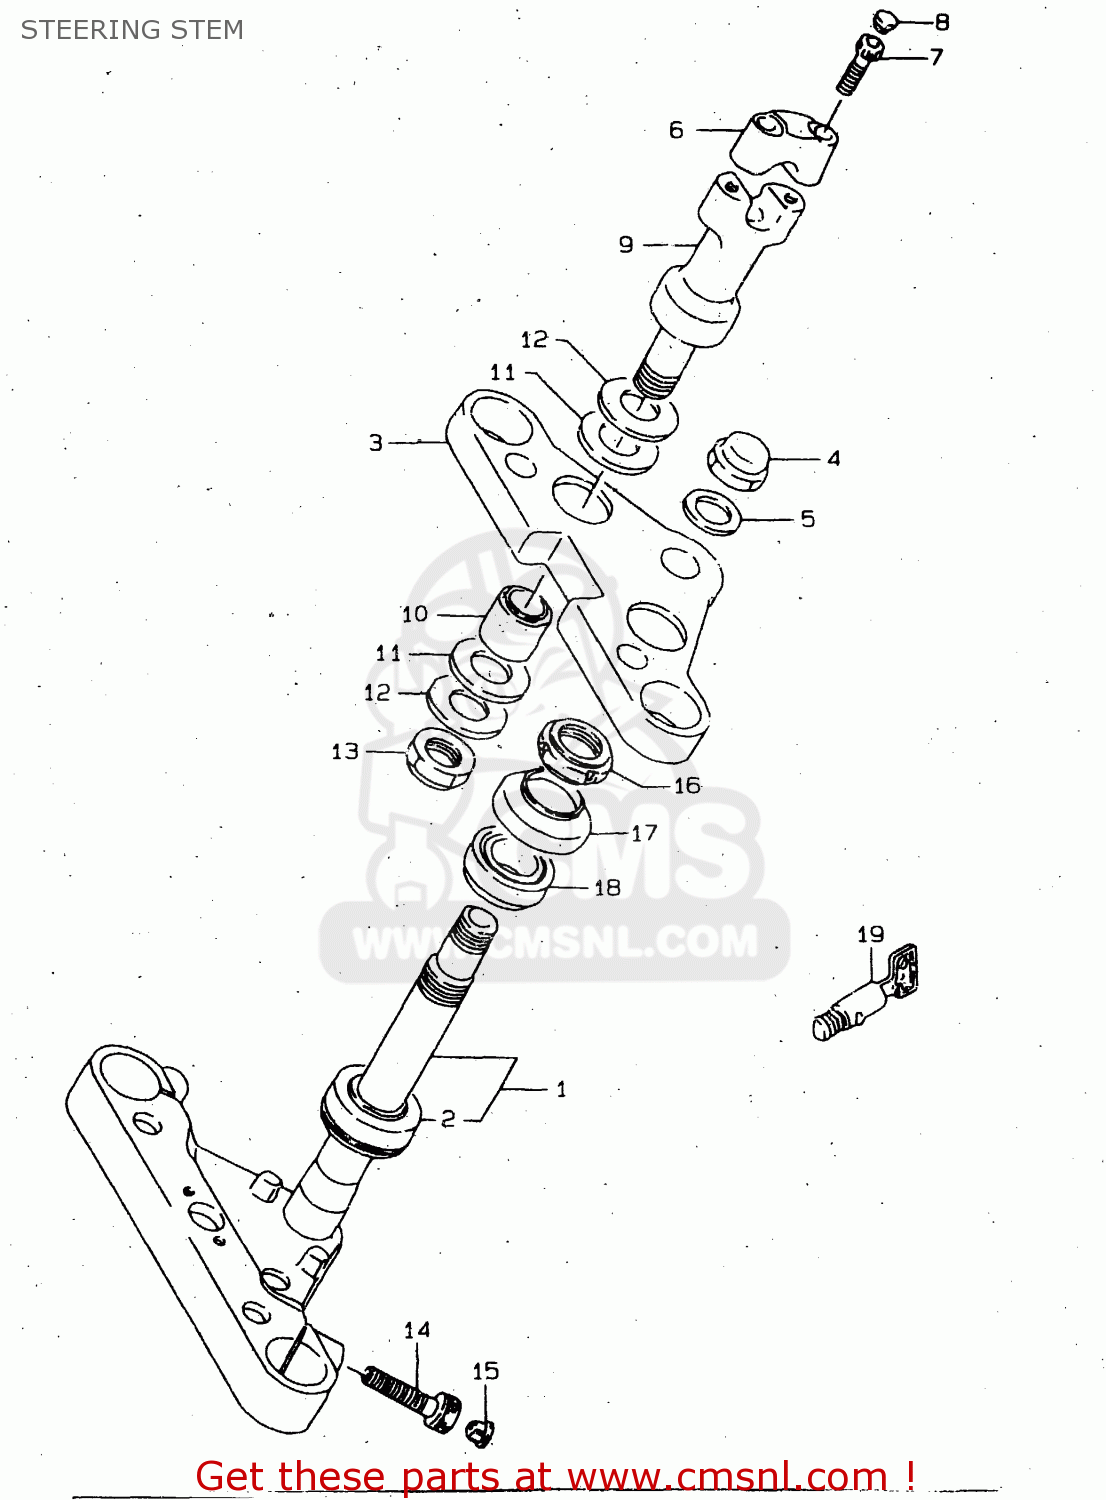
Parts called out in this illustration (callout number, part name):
1	STEM,STEERING
2	BEARING(30X55X17)
3	HEAD,STEERING STEM
4	NUT,CAP
5	WASHER(22.5X32X1.6)
6	HOLDER,HANDLE UPR
7	BOLT
8	CAP(OD:14.5)
9	HOLDER,HANDLE
10	CUSHION
11	SEAT,RUBBER
12	WASHER
13	NUT
14	BOLT
15	CAP(OD:12)
16	NUT,STEERING STEM(25X44X10)
17	SEAL,STEERING UPR DUST
18	BEARING(25X47X15)
19	LOCK SET,STEERING
